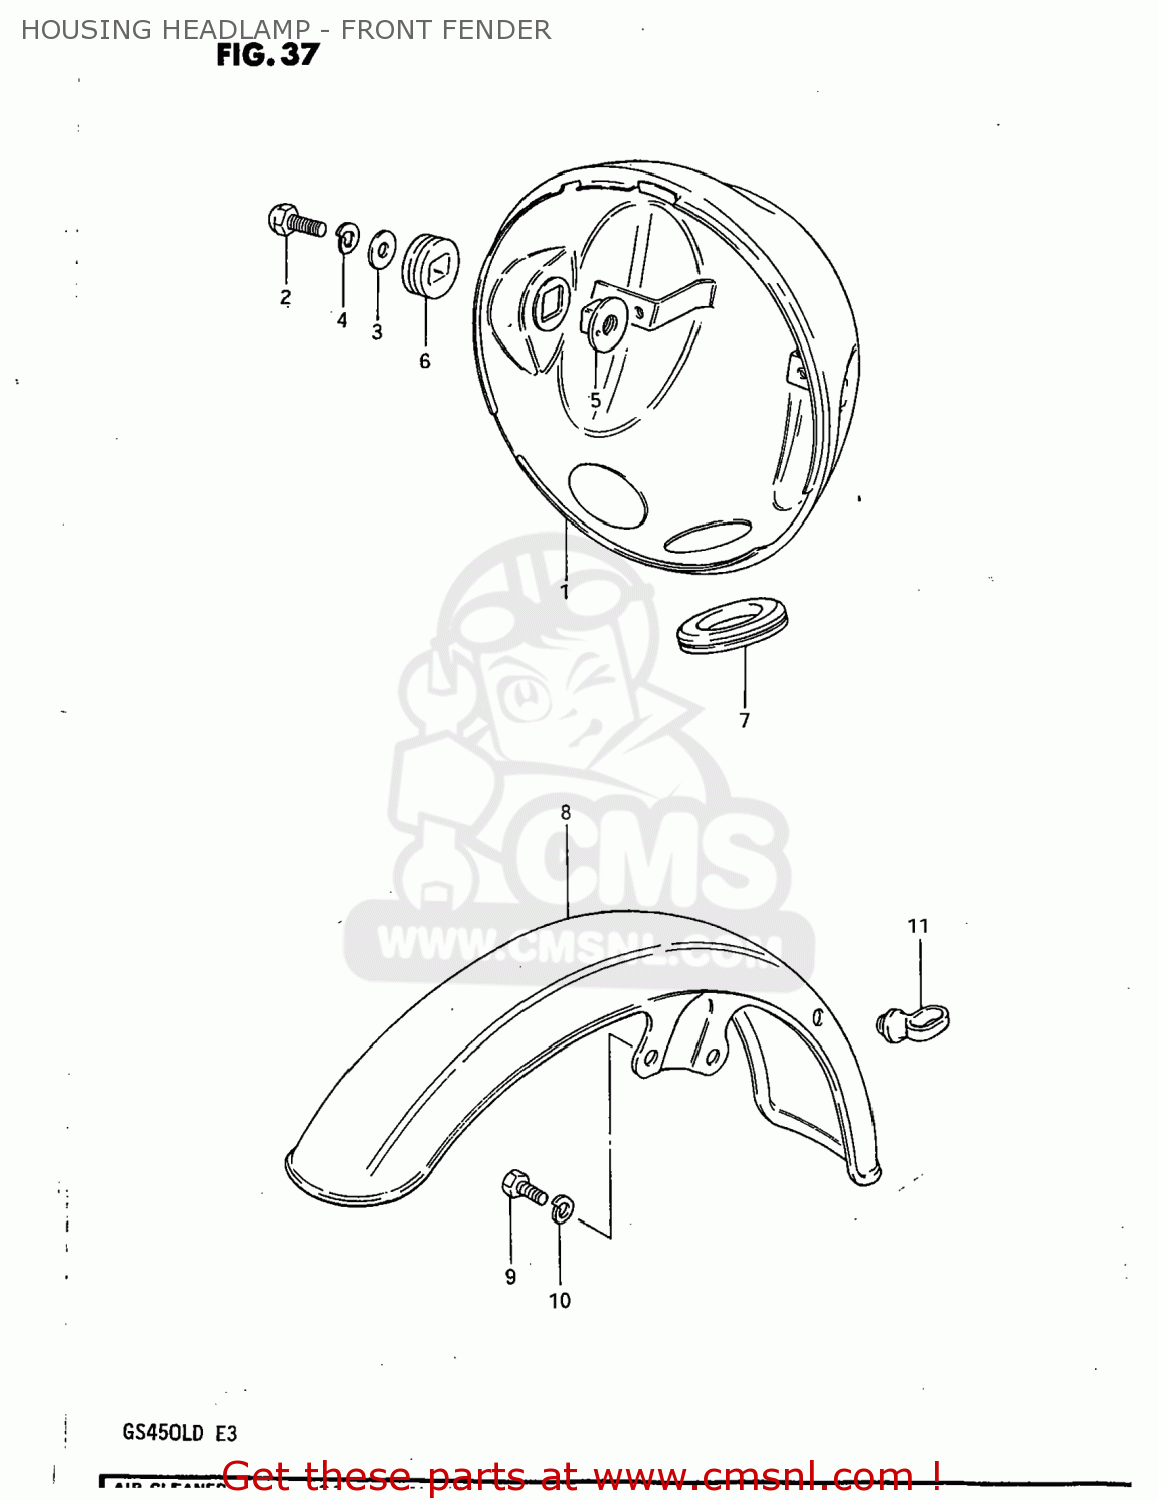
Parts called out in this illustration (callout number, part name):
1	HOUSING,HEADLAMP
2	BOLT
3	WASHER
4	LOCK WASHER
5	SPACER,HEADLAMP HOUSING
6	CUSHION,HEADLAMP HOUSING
7	GROMMET,HEADLAMP HOUSING
8	FENDER,FR
9	BOLT
10	LOCK WASHER
11	GUIDE,CABLE
